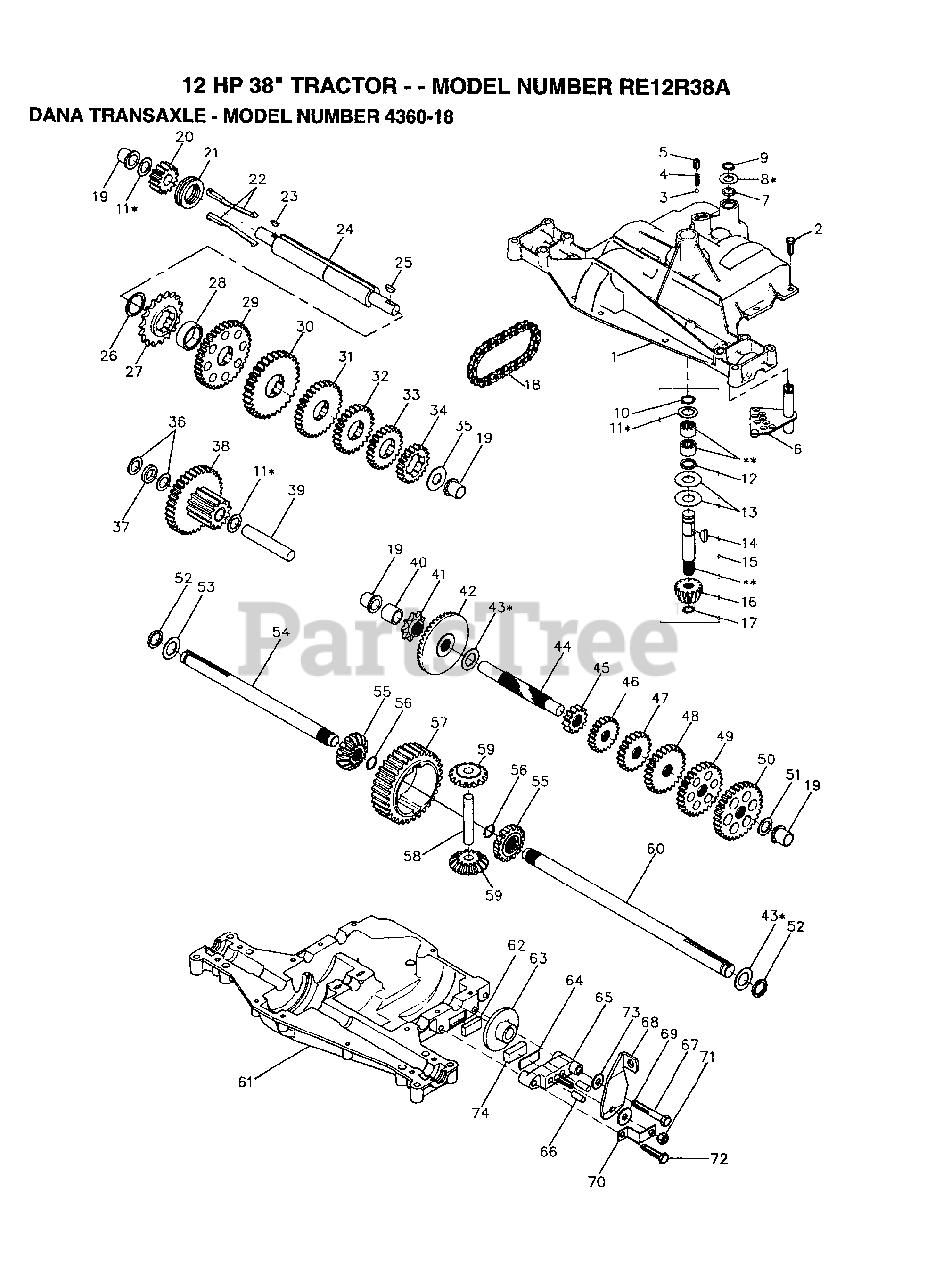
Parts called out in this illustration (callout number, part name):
1	HOUSING UPPER
3	BALL DETENT
4	SPRING, DETENT
5	SCREW, SET
6	ASSY SHIFTER
8	WASHER PLAIN
9	RING RETAINING
10	RING RETAINING
11	WASHER PLAIN
13	WASHER, PLAIN .632 X 1.38 X .046
14	KEY WOODRUFF #9
15	ASSY KIT INPUT SHAFT
16	PINION, BEVEL, 14 TEETH
17	RING, RETAINING
18	CHAIN, 24 PITCHES
19	BEARING, FLANGE
20	GEAR SPUR, 14 TEETH
21	COLLAR CLUTCH
22	KEY CLUTCH
23	KEY WOODRUFF #3
24	SHAFT INTERMEDIATE
25	KEY, WOODRUFF, #61
26	RING, RETAINING
27	SPROCKET, 18 TEETH
29	GEAR, SPUR, 37 TEETH
30	GEAR, SPUR, 35 TEETH
31	GEAR, SPUR, 30 TEETH
32	GEAR, SPUR, 25 TEETH
33	GEAR, SPUR, 22 TEETH
35	WASHER, PLAIN .640 X 1.37 X .061
36	WASHER, PLAIN .632 X 1.00 X .026
37	SPACER .630 X 1.00 X .169
38	ASSY GEAR COMB 12&35 TEETH
39	SHAFT IDLER
40	SPACER .635 X .875 X .755
41	SPROCKET, 9 TEETH
42	GEAR, BEVEL, 42 TEETH
43	WASHER PLAIN
44	SHAFT, DRIVE
45	GEAR, SPUR, 12 TEETH
46	GEAR SPUR, 15 TEETH
47	GEAR, SPUR, 20 TEETH
48	GEAR, SPUR, 25 TEETH
49	GEAR, SPUR, 28 TEETH
50	GEAR, SPUR, 31 TEETH
51	WASHER, PLAIN .632 X 1.00 X .060
53	WASHER PLAIN
54	AXLE LEFT HAND
55	GEAR, MITER, 15 TEETH
56	RING, RETAINING
57	GEAR, SPUR, 32 TEETH
58	SHAFT, CROSS
59	GEAR, MITER, 15 TEETH
60	AXLE RIGHT HAND
61	HOUSING LOWER
62	PUCK, FRICTION
63	DISC, BRAKE
65	JAW, BRAKE
66	PIN, DOWEL
67	SCREW TAPPING
68	LEVER, ACTUATING
69	WASHER, PLAIN .321 X 1.00 X .055
70	BRACKET, ANTI-ROTATION
71	LOCKNUT 5/16-24
72	SCREW TAPPING
73	WASHER PLAIN
74	PUCK, FRICTION
